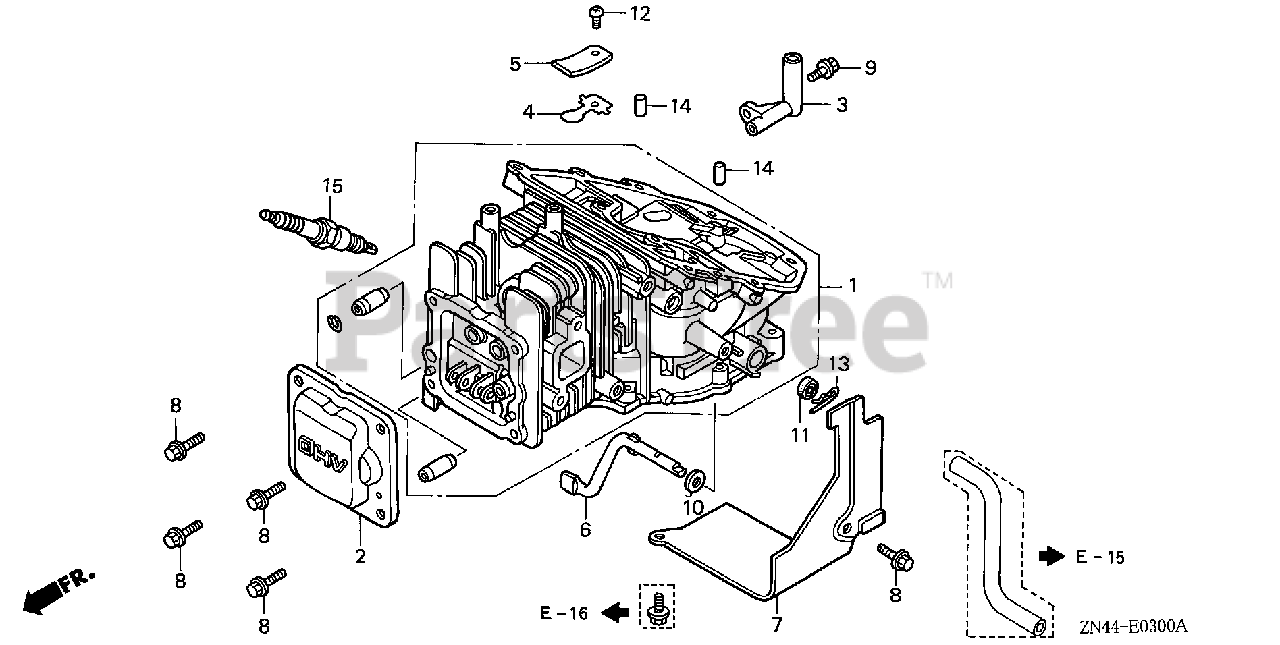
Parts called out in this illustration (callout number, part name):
1	CYLINDER
2	COVER, HEAD
3	PIPE, BREATHER
4	VALVE, OIL OUTLET
5	PLATE, STOPPER
6	SHAFT, GOVERNOR ARM
7	SHROUD
8	BOLT, FLANGE (5X12)
9	BOLT (4X10)
10	WASHER (5.2X9)
11	OIL SEAL (5X11X5)
12	SCREW, PAN (3X5)
13	PIN, LOCK (6MM)
14	ROLLER (6X15)
15	SPARK PLUG (U14FSR-UB) (DENSO)
15	SPARK PLUG (CR4HSB)
15	SPARK PLUG (U16FSR-UB) (DENSO)
15	SPARK PLUG (CR5HSB)
